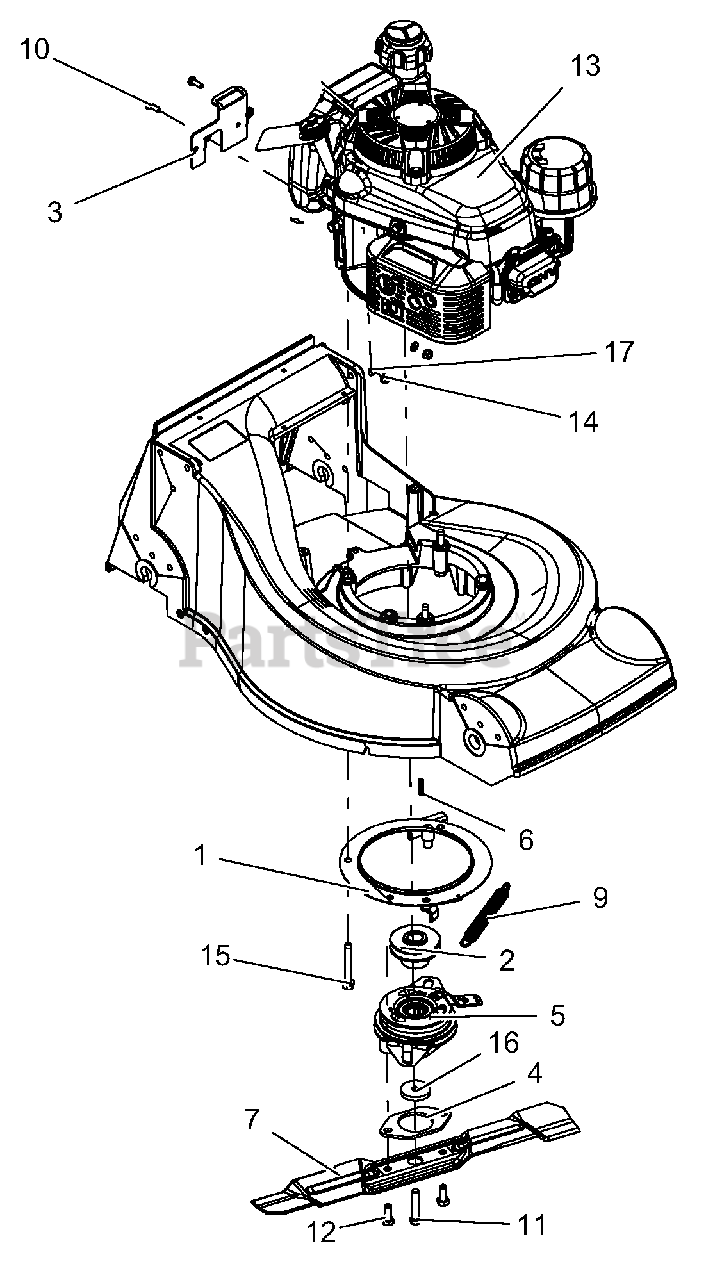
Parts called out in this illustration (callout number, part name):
1	WLDMT, PLATE -BBC
2	PULLEY, SP, KAWI, BBC
3	BRKT, FUEL TANK
4	SPCR, BBC BLADE
5	KAWASAKI, BBC
6	KEY 3/16 X 3/16 X 1
7	BLADE, MOWER 21" HIGH-LIFT
9	SPRG, EXTENSION BBC
10	BLT-HEX .25-20X.75 GR5 YWZC
11	BLT-HEX .38-24X2.00 YWZC GR8
12	BLT-HEX M10 X 1.5X20 GR5 YWZC
13	ENGINE, KAWASAKI BBC CARB
14	NUT, LK-TOP-FLG .25-20 YWZC
15	SCR-TAP.375-16X2.75 HWH TR YZ
16	WSHR-FL-STL .400X1.75X.250
17	WSHR-FL-STL.250X.562X.049YWZC
